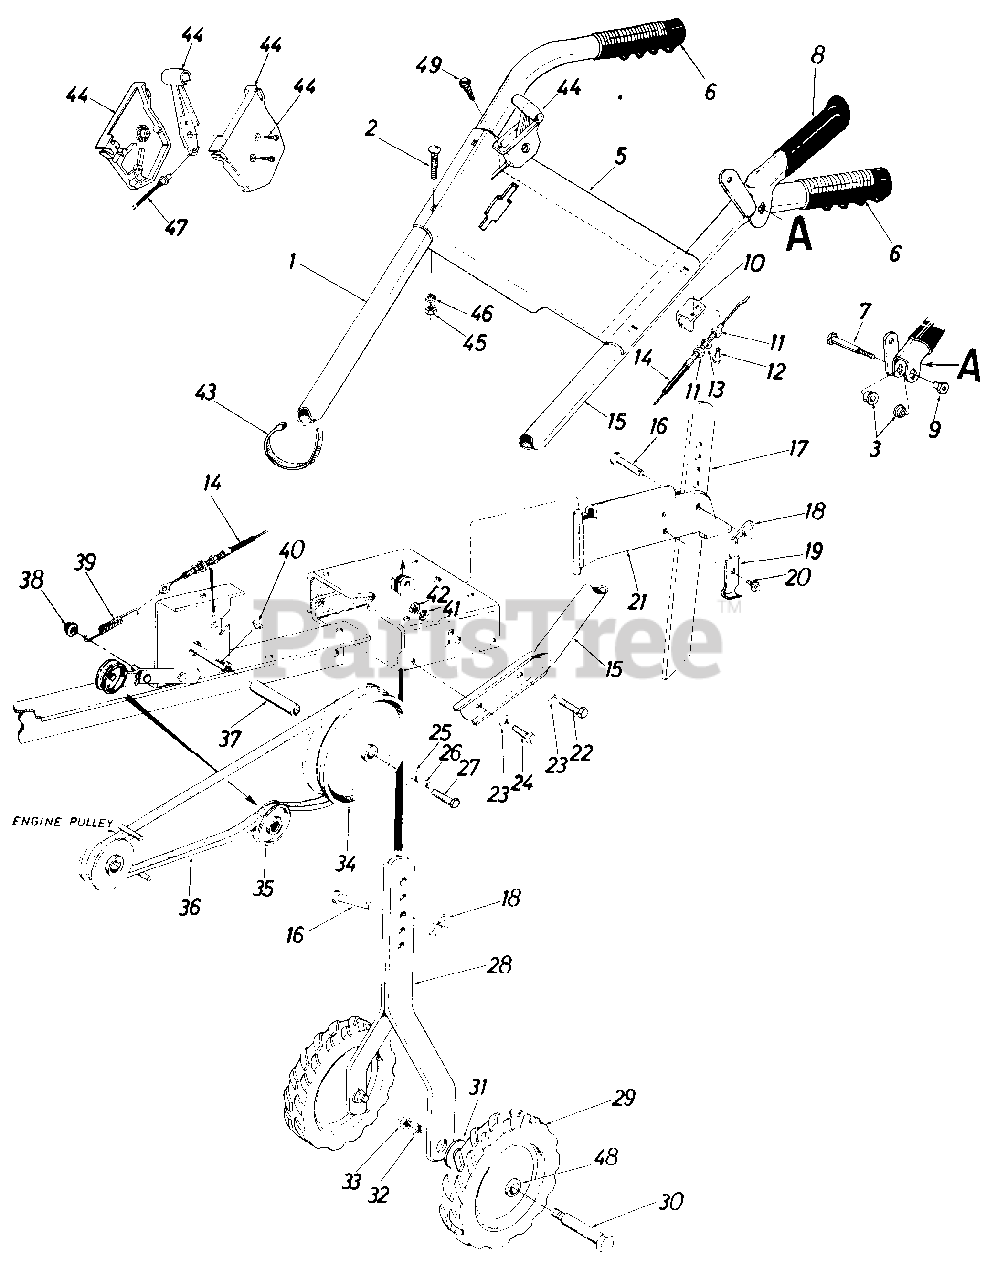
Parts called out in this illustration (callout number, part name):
1	Handle R.H.
2	Carriage Bolt 5/16-18 x 1.75" Lg.
3	Hex Flange Plastic Brg.
5	Handle Panel
6	Grip
7	Shld. Bolt .38" Dia.
8	Clutch Grip Ass'y.
9	Shld. Nut 1/4-20 Thd.
10	Cable Support Brkt.
11	Hex Jam Nut 5/16-24 Thd.
12	Hex Wash. Hd. Self-Tap Scr. 1/4-20 x .50" Lg.
13	L-Wash. 5/16" I.D.
14	Clutch Control Cable
15	Handle L.H.
16	Clevis Pin
17	Depth Bar
18	Hairpin Cotter
19	Depth Bar Spring
20	Hex Wash. Hd. Self-Tap Scr. 1/4-20 x .50" Lg.
21	Tailpiece Ass'y.
22	Hex Scr. 3/8-16 x 1.00" Lg.
23	Belleville Wash. 3/8" I.D.
24	Hex Wash. Hd. Self-Tap Scr. 318-24 x 718" Lg.
25	Fl-Wash. .25" I.D. x .930" O.D. x .120" Thk.
26	L-Wash. 1/4" I.D.
27	Hex Scr. 1/4-28 x .751' Lg.
28	Wheel Bracket Ass'y.
29	Wheel Ass'y. 10 x 1.75
30	Shld. Bolt
31	Belleville Washer 1/2" I.D.
32	L-Wash. 1/2" Scr.
33	Hex Nut 1/2-20 Thd.
34	Pulley 6.00" O.D.
35	Idler Pulley
36	V-Belt 1/2" Pitch x 39"
37	Spacer
38	Cap Speed Nut
39	Extension Spring
40	Hi-Pro Key
41	L-Wash. 3/8" Scr.
42	Hex L-Nut 3/8-16 Thd.
43	Cable Ties
44	Throttle Control Box
45	Hex Nut 5/16-18 Thd.
46	L-Wash. 5/16" Scr.
47	Throttle Control Wire 35"
48	Bearing
49	Self-Tapping Scr. #10 x .50" Lg.
